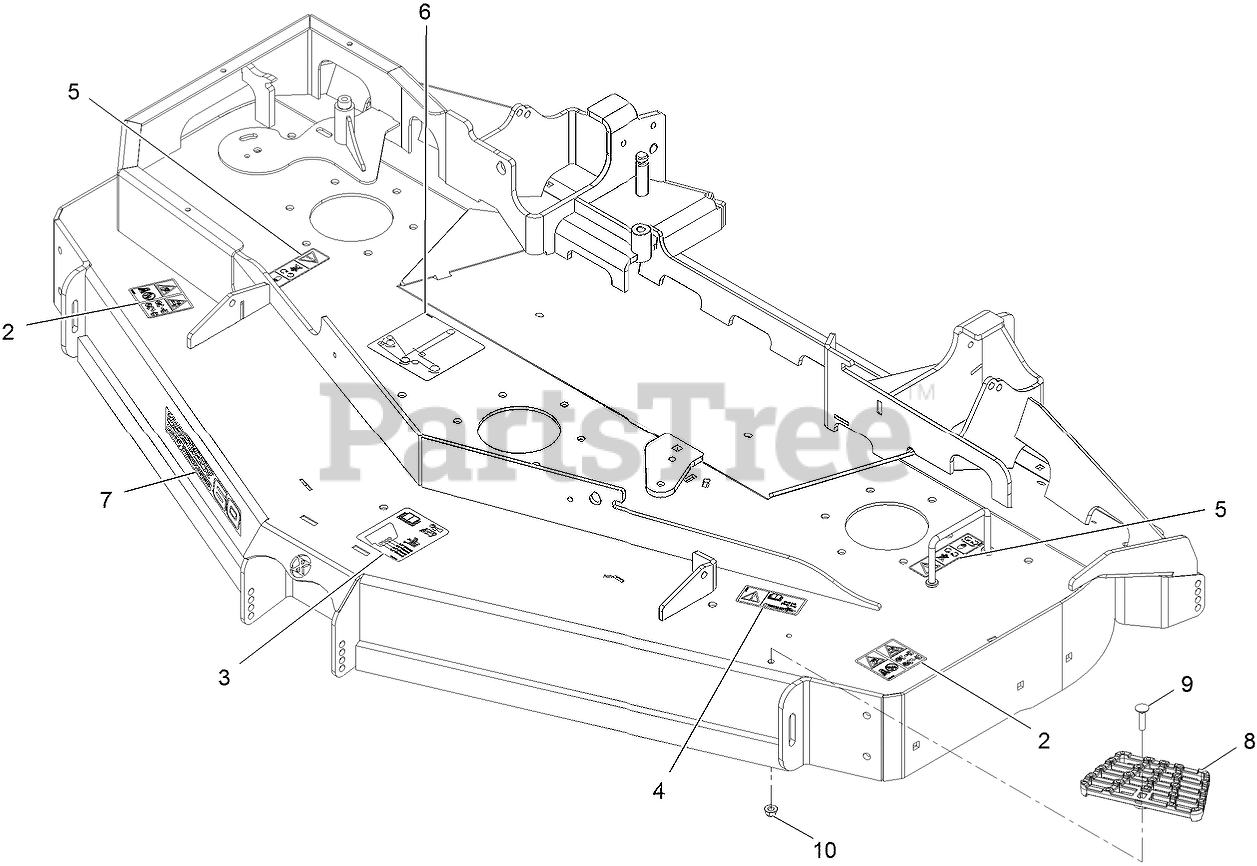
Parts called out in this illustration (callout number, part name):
2	DECAL-DANGER, THROWN OBJECT
3	DECAL-ROLLER, ANTI-SCALP
4	DECAL-BOLT TORQUE
5	DECAL-COVER, MISSING
6	DECAL-ROUTING, BELT
7	Decal, 60Rd
8	STEP-DECK
9	Bolt-Carriage 5/16-18 X 1 1/4
10	NUT-HF, NI
